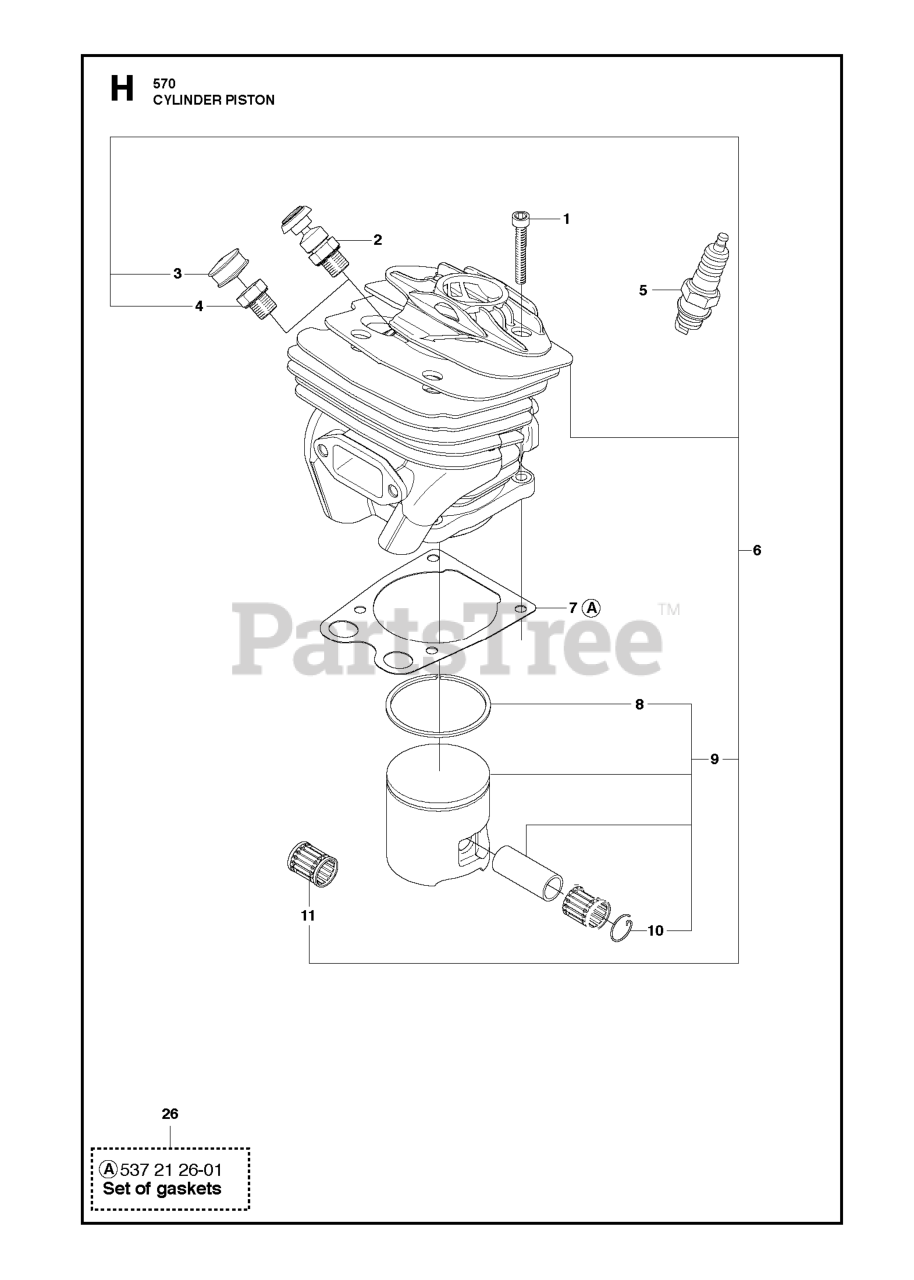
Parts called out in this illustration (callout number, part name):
1	SCREW MC6S 5X25
2	VALVE
4	CYLINDER PLUG
5	SPARK PLUG RCJ7Y
8	PISTON RING
9	PISTON 49 MM
10	WRIST PIN CLIP
11	SUPPORT BUSHING
26	GASKET SET
